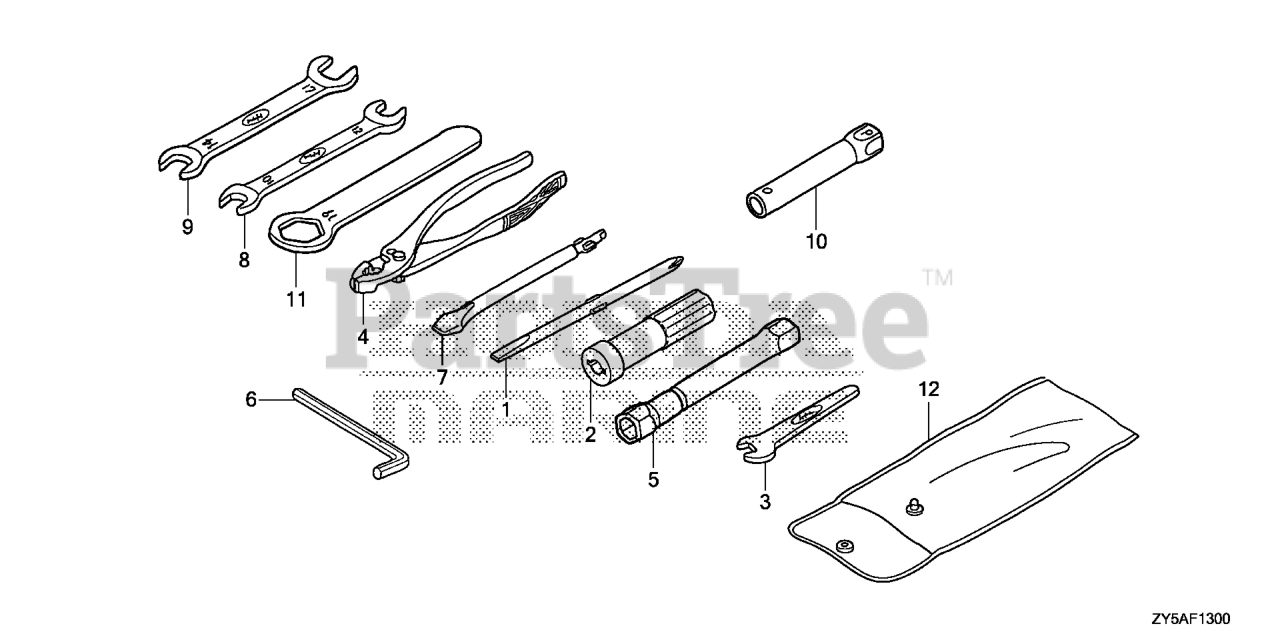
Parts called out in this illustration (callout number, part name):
1	SCREWDRIVER (NO.2 PHILLIPS -)
5	WRENCH, PLUG
6	WRENCH, HEX. (6MM)
11	WRENCH, EYE (19MM)
12	BAG, TOOL (230MM)
